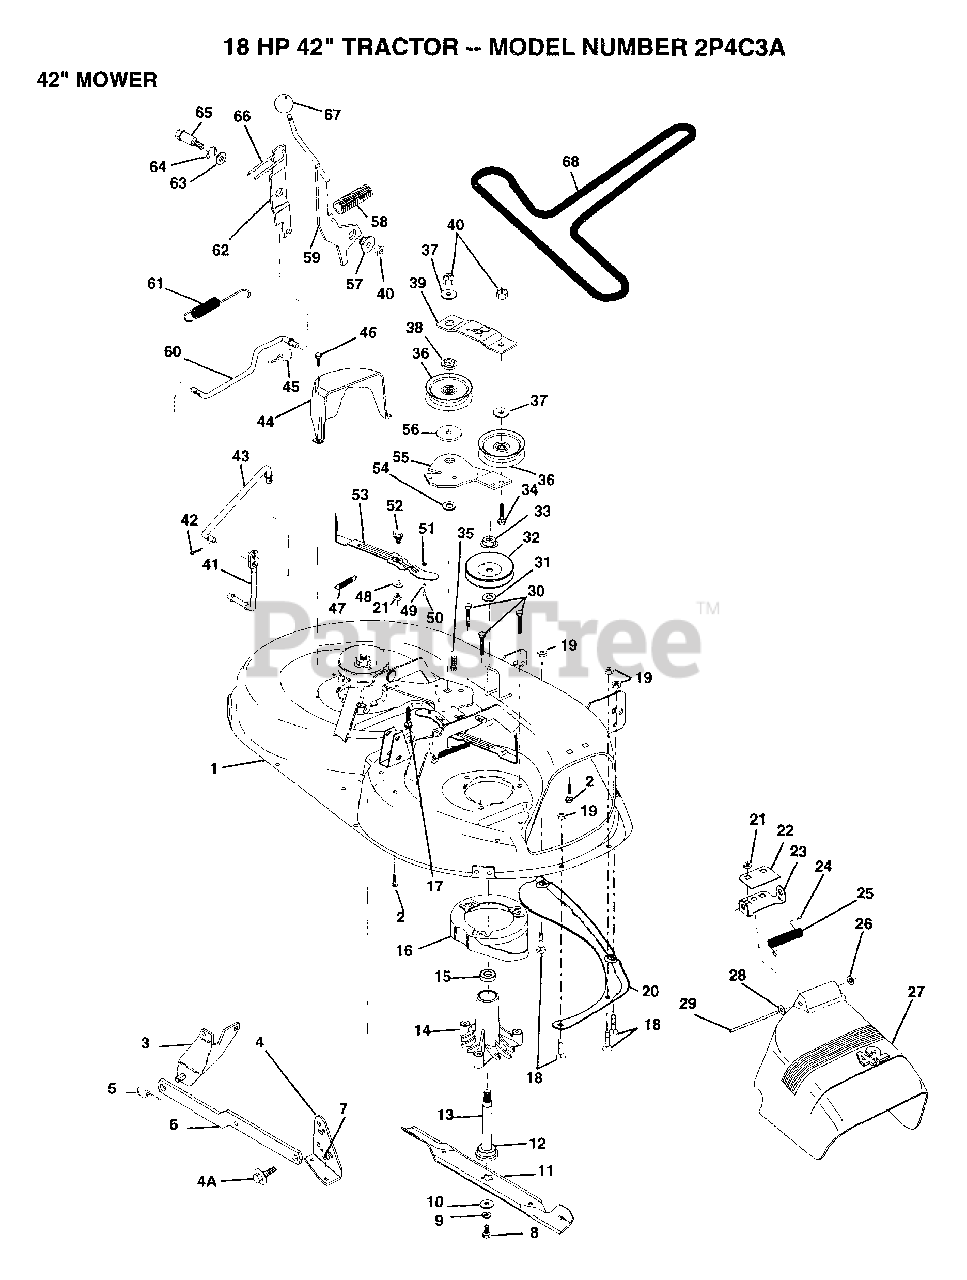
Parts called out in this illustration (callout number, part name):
2	BOLT
3	BRKT ASM SWAY BAR
4	BRKT DECK SW BAR
4A	BOLT SHD 5/16-18
7	NUT
8	BLADE BOLT
10	WASHER BLADE
11	"BLADE.42"" HIPERF"
12	BEARING.BALL
14	HSG ASM MANDREL
15	BEARING
17	BOLT CARRIAGE
18	BOLT
19	NUT
22	STIFFENER BRKT
23	DEFLECTOR BRKT
24	CAP-SLEEVE LT
25	SPRING TORSION
26	NUT PUSH M
27	DEFLECTOR.SHIELD
28	WASHER
29	HINGE ROD
31	WASHER
34	BOLT
35	XMAS TREE FASTNER
36	FLAT IDLER PULLEY
37	WASHER GT
38	RETAINER SPACER
39	IDLER ARM STIFF
41	PIVOT ROD
43	CLUTCH ROD SECOND
45	RETAINER M
46	SCREW LT
47	SPRING EXTENSION
48	HARD SMALL WASHER
50	SHOULDER BOLT
51	LOCKNUT
53	BRAKE PAD ARM ASM
54	HARDENED WASHER
55	IDLER ARM
56	SPACER RETAINER
57	BUSHING
59	LEVER.ASM.CLUTCH
60	"ROD, CLUTCH PRIM"
61	RETURN SPRING
62	RETURN SPRING
62	CLUTCH ARM SECOND
63	WASHER
64	RING
65	SHOULDER BOLT
66	SPRING KEEPER
68	BELT-V.92.4.MWR
